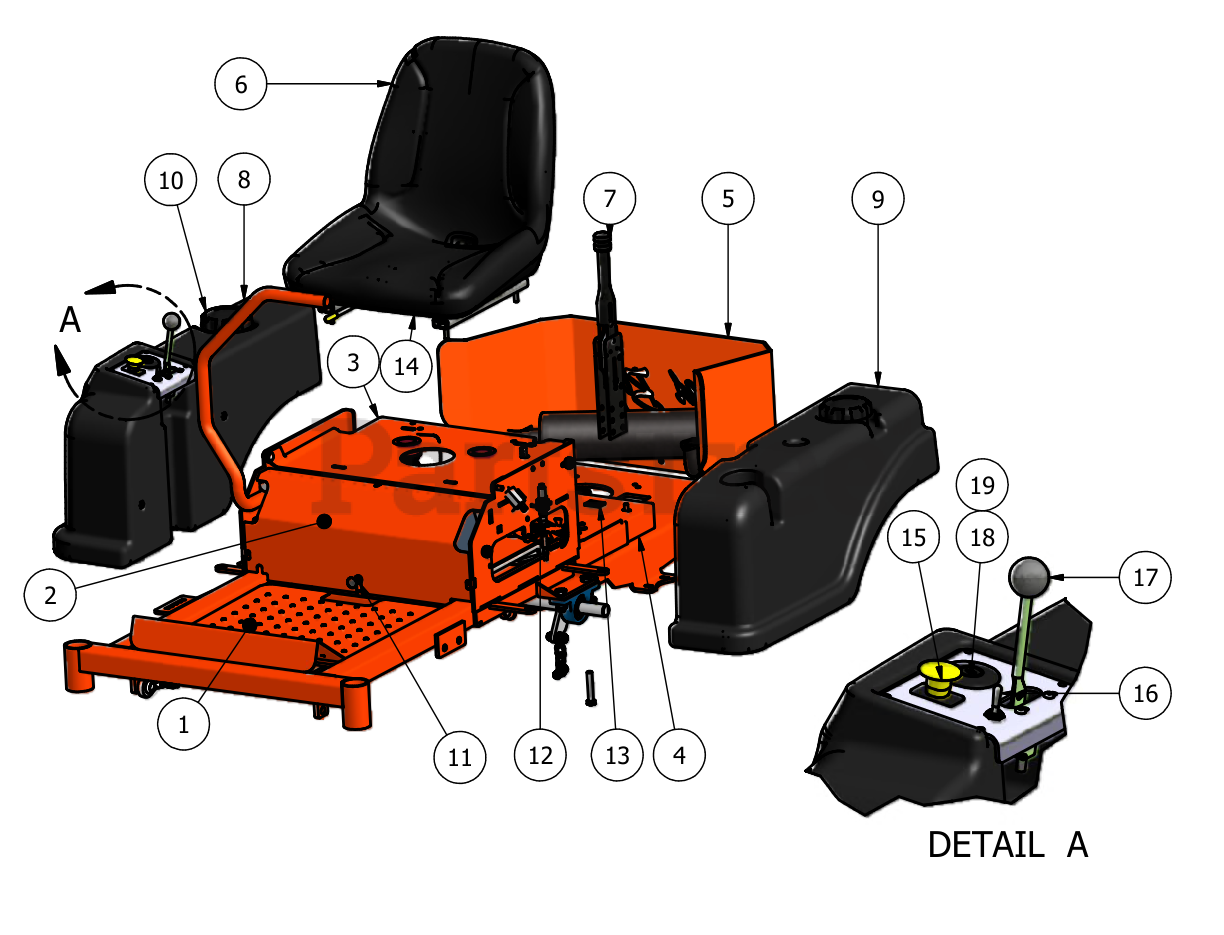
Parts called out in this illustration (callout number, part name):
1	ZT Floor Panel
2	Cooler Cover
3	Seat Mounting Plate
5	ZT Rear Plate
6	Seat Assembly
7	Hand Brake
8	Right Tank
12	Brake Cable
13	Tachometer
14	Seat Safety Switch
15	PTO Engager
18	Ignition Switch
